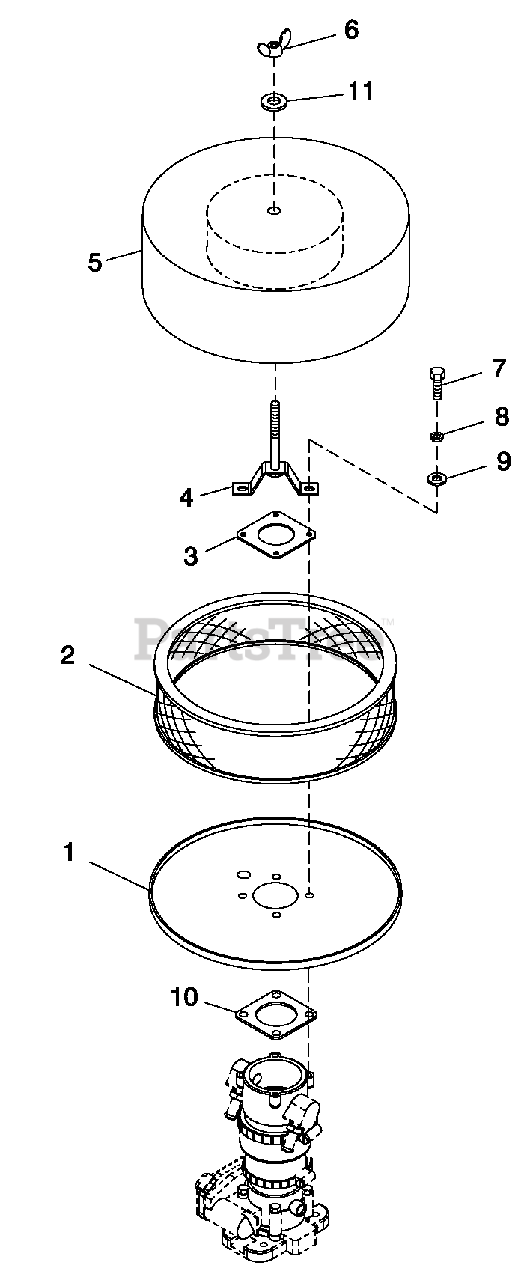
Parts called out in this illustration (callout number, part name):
1	AIR CLNR BTM PLT W/CPLR 8.1L
2	ELEMENT AIR FILTER
3	TOP PLATE VENTURI
4	HOLD DOWN AIR CLEANER PLATED
5	PLATE AIR CLEAN TOP 5.4L/6.8L
6	NUT WING 1/4-20 NYLK
7	SCREW HHC M6-1.0 X 16 G8.8
8	WASHER LOCK M6-1/4
9	WASHER FLAT M6
10	GASKET MIXER BODY
11	WASHER FLAT 1/4-M6 ZINC
